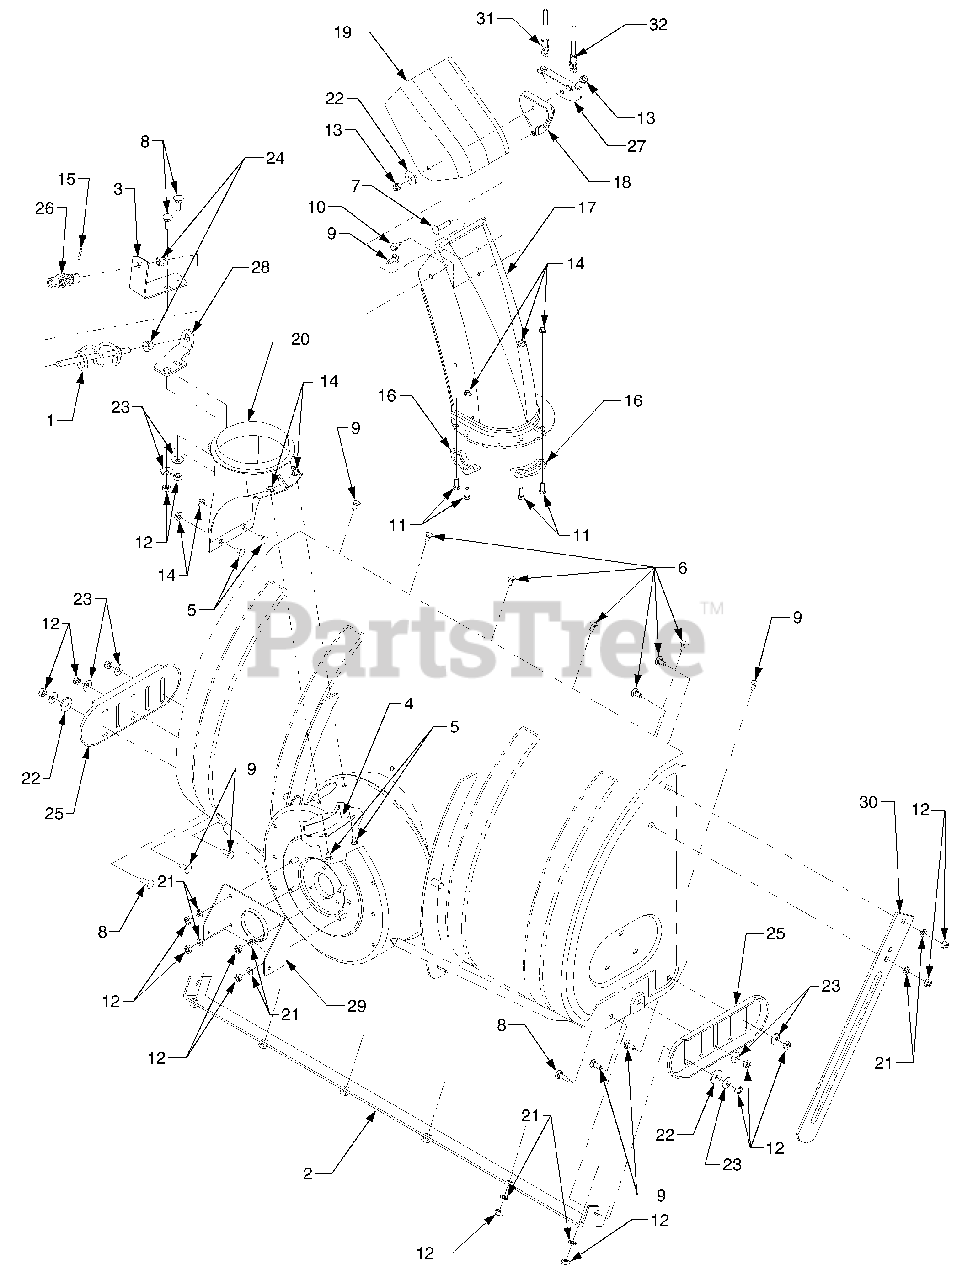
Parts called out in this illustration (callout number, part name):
1	Chute Crank
2	Plate, Shave
3	Bracket, Chute Crank
4	Plate, Chute Reinforcement
5	Bolt, Carriage, 1/4-20 x .5
6	Bolt, Carriage, 5/16-18 x .62
7	Bolt, Carriage, 5/16-18 x 1.5
8	Bolt, Carriage, 5/16-18 x 1.0
9	Bolt, Carriage, 5/16-18 x .75
10	Screw, Hex Wash. Hd. Tapp 1/4-14 x .625
11	Screw, Hex Cap 1/4-20 x .75 GR5
12	Nut, Hex, 5/16-18 GR2 22
13	Nut, Hex Insert Lock, 5/16-18
14	Nut, Hex Flange Lock, 1/4-20
15	Pin, Spirol, 1/8 x .812
16	Keeper, Chute Flange
17	Chute, Lower Discharge
18	Guide, Cable
19	Chute, Upper Discharge
20	Adapter, Discharge Chute
21	Washer, Lock, 5/16
22	Washer, Flat, .344 x 1.125 x .12
23	Washer, Bell, .34 x .872 x .06
24	Bushing, Plastic
25	Shoe, Skid
26	Block Assembly, Joint
27	Bracket, Cable
28	Bracket, Chute Crank
29	Bracket, Box Mounting
30	Guide, Blade
31	Cable, Chute Control
32	Cable, Chute Control w/Clip
